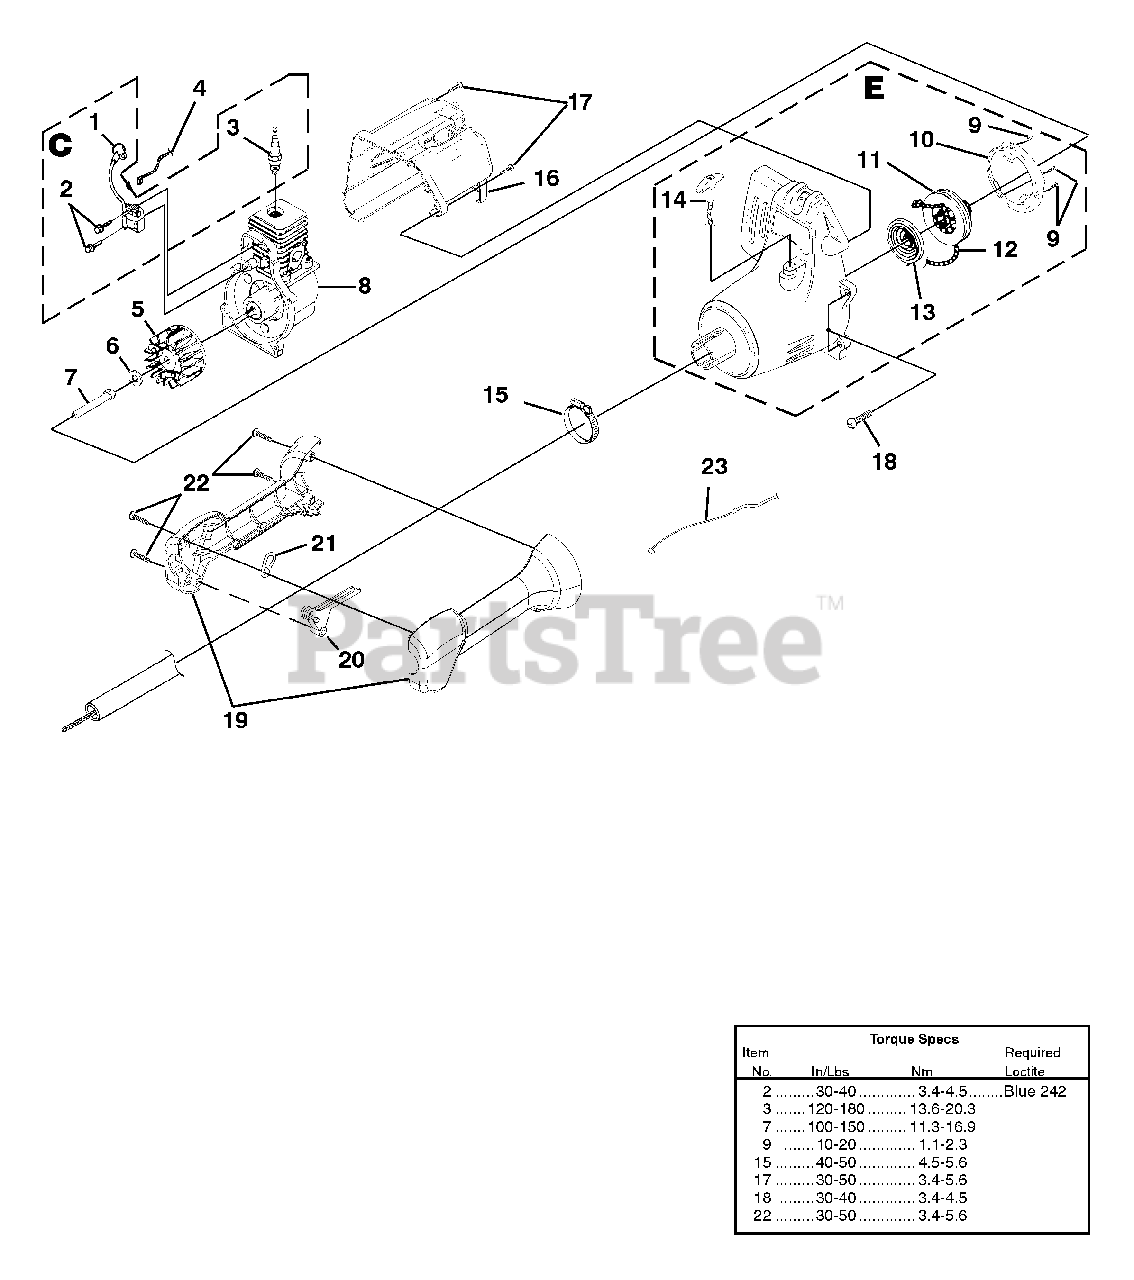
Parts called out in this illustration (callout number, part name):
1	TERMINAL & COVER
2	SCREW-Taptite (8-32 X 1")
3	SPARK PLUG
4	LEAD-Electrical
5	ROTOR
6	WASHER-Flat
7	CONNECTOR-Drive (.250)
8	SHORT BLOCK
9	SCREW-Taptite (8-16 X 1/2")
10	BAFFLE-Air
11	PULLEY-Starter
12	ROPE-Starter (42")
13	SPRING & CONTAINER
14	GRIP-Starter
15	CLAMP
16	HOUSING-Rear Kit
17	SCREW-Taptite (10-14 X 7/8")
18	SCREW-Taptite (10-24 X 3/4")
19	CONTROL HANDLE ASSY.
20	TRIGGER-Throttle
21	HOOK-Harness
22	SCREW-Taptite (10-14 X 7/8")
23	CABLE-Throttle
C	IGNITION
E	COMPLETE STARTER ASSEMBLY
